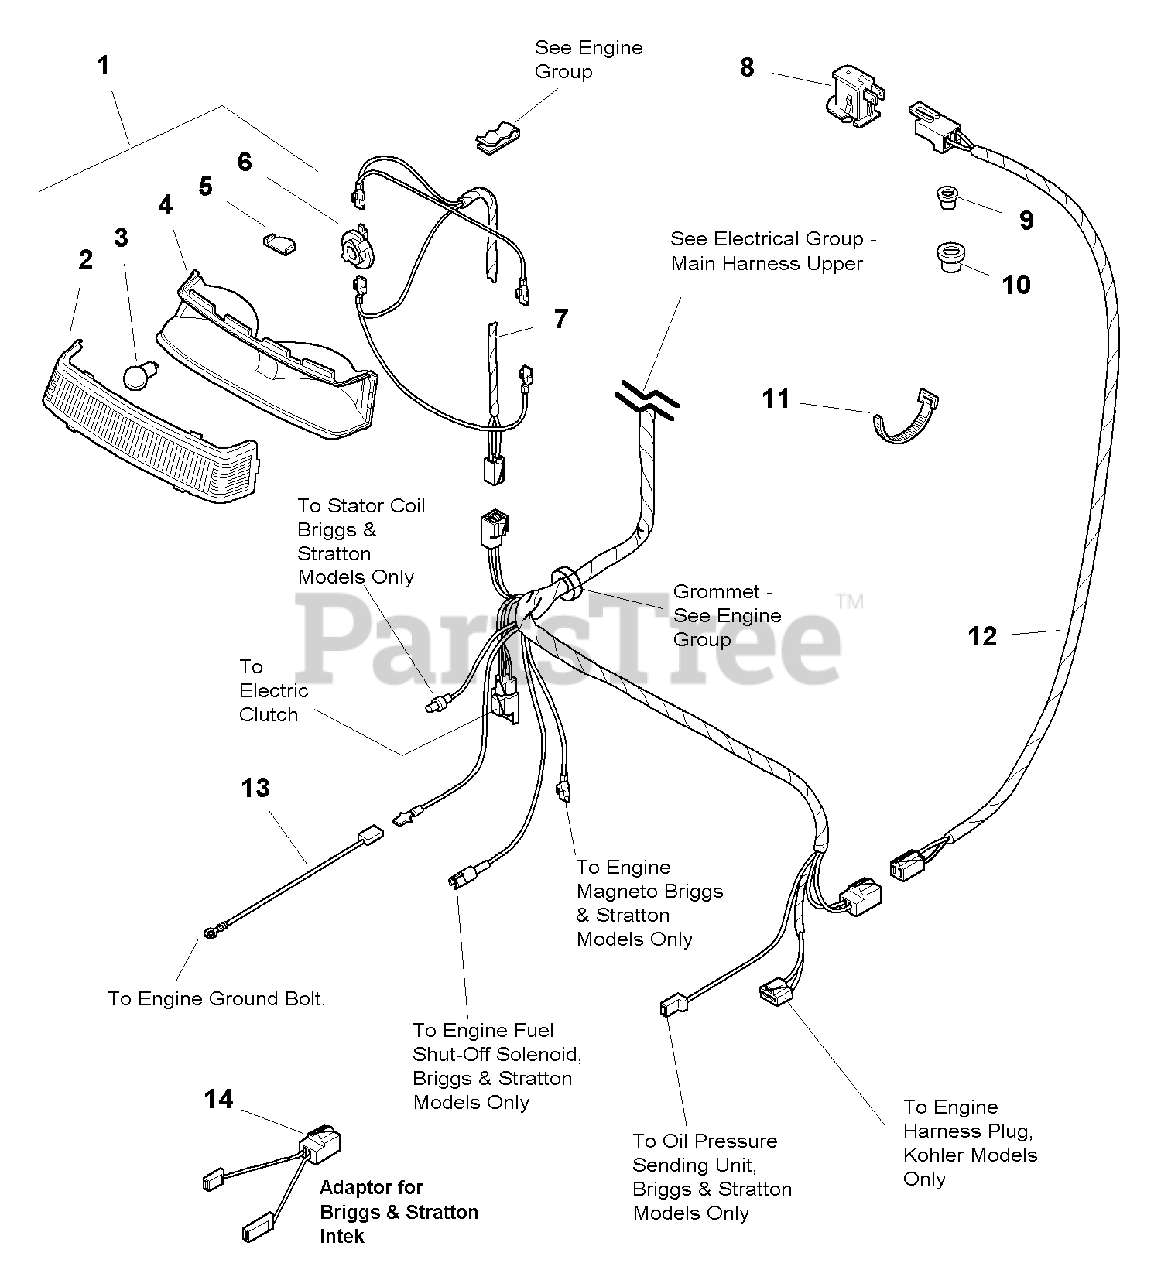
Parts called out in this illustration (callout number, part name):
1	HEADLIGHT ASSEMBLY (Includes Ref. Nos. 2, 3, 4, 5 & 6)
2	LENS, Headlight
3	BULB, Headlight, 12.8V
4	BEZEL, Headlight
5	HEAT SHIELD
6	SOCKET, Bulb
7	WIRE ASSEMBLY, Headlight
8	SWITCH, Seat, Operator Present
9	BUSHING, Snap, Small
10	BUSHING, Snap, Large
12	WIRE ASSEMBLY, Seat Switch
13	WIRE ASSEMBLY, Engine Ground
14	WIRE ASSEMBLY, Harness Adaptot for B & S Intek
